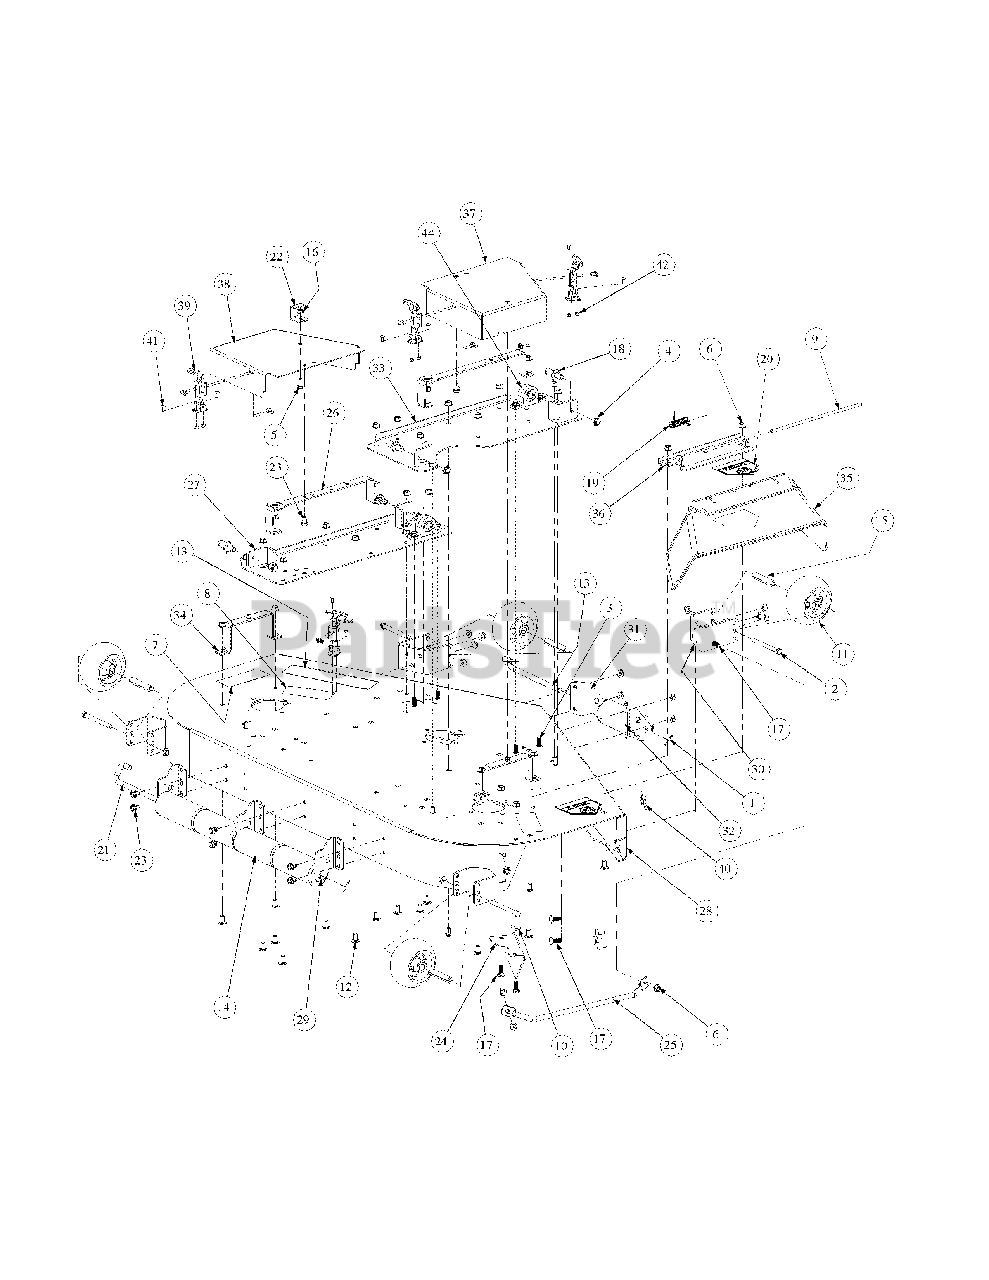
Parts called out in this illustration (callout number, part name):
1	Cotter Pin, .125 Dia x 1.0
2	Hex Cap Screw, 3/8-16, 3.75
3	Carriage Screw, 3/8-16 x 1.25
4	Lock Nut, Nylon Insert, 1/2-13
5	Hex Cap Screw, 5/16-18 x 3/4
6	Hex Nut, 3/8-16 Flange Lock
7	Decal Rotating Blade
8	Decal, Warning Shield Missing
9	Deflector Chute Rod
10	Idler Washer
11	Complete Wheel, 5.00 Dia.
12	Carriage Bolt, 3/8-16 x .75 Lg.
13	Roller Pin. 1/2 Dia. x 7.31 Lg.
14	Front Roller
15	Wheel Spacer
16	Hexflange Lock Nut, 5/16-18
17	Carriage Bolt, 3/8-16 x 1
18	Pin, 5/8 Dia. x 1.2 Lg.
19	Spring Torsion, 0.4 ID x 2.16 LG
20	Decal, Danger Hands and Feet
21	Roller Pin
22	Tension Rod Stop Bracket
23	Hex Index Washer Screw, 3/8-16, .5
24	Chute Bracket
25	Finger Guard
26	Cover Support
27	Left Hand Mount, Deck Bracket Assembly
28	54" Deck Assembly
29	Roller Mount Bracket
30	Anti-Scalp Wheel, Front Mount Bracket
33	Deck Bracket Assembly
34	Outer Belt Cover Support Assembly
35	Deflector Chute
36	Deflector Chute Bracket
37	Right Hand Belt Deck Cover
38	Left Hand Belt Deck Cover
39	T-Handle Draw Latch
40	Decal, 54"
41	Phillips Head Screw, 10-32
42	Lock Nut, Nylon Insert, 10-32
43	Mower Deck Label
44	Pillow Block
